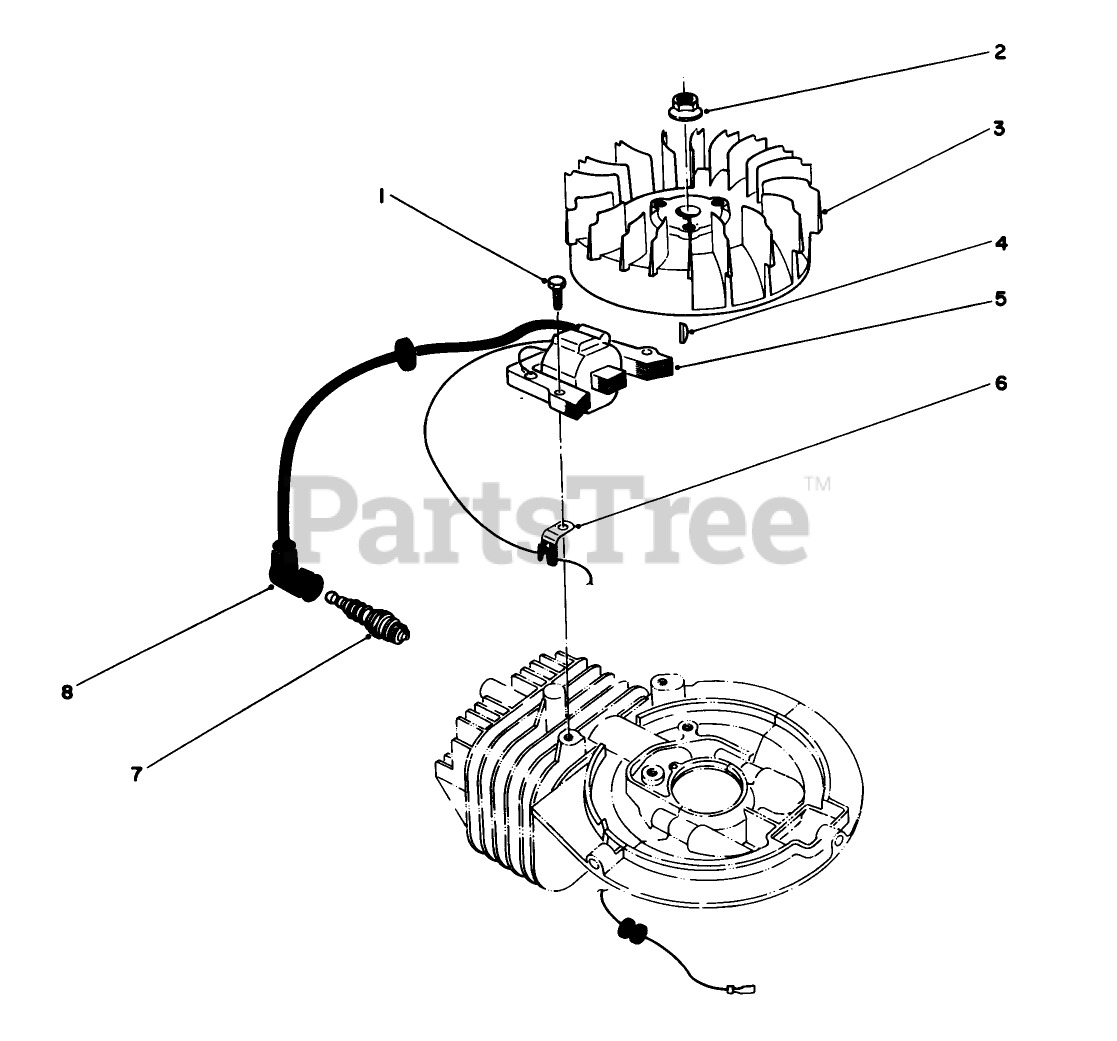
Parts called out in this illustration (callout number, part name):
1	SCREW
3	FLYWHEEL
5	COIL-MAGNETO
6	CLAMP
7	SPARK PLUG
8	CAP-SPARKPLUG
